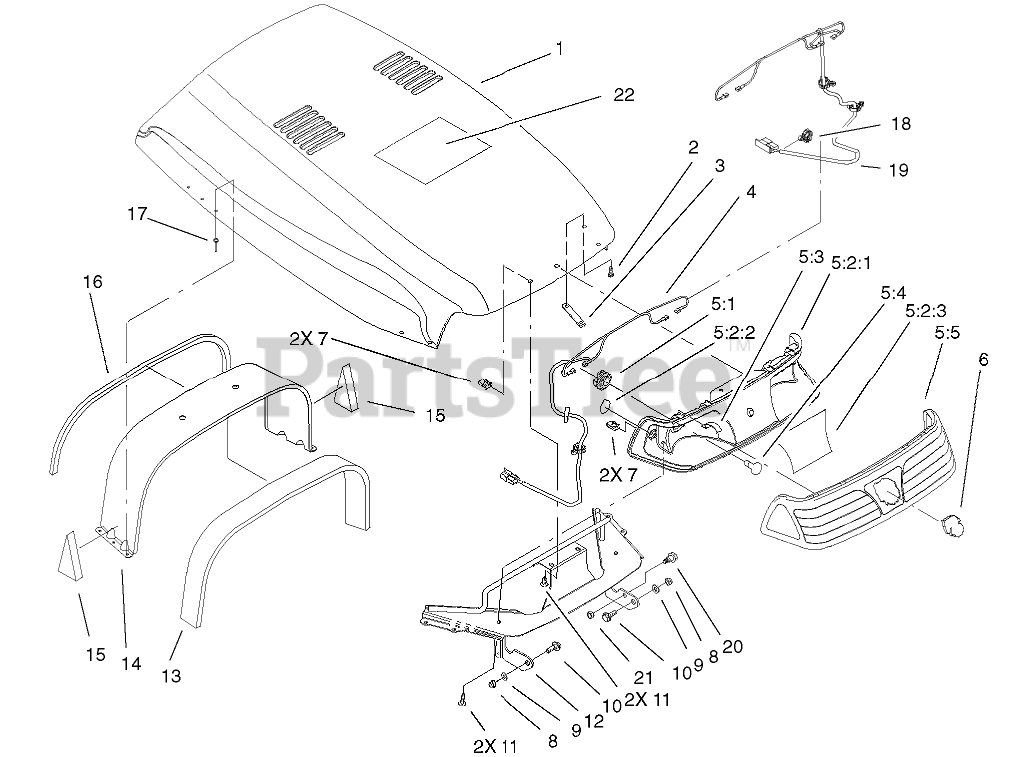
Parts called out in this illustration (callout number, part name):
1	HOOD ASM
2	SCREW
3	PLATE-NUT
4	HARNESS-WIRE, LIGHTS
5:1	SEALED SOCKET ASM
5:2:1	REFLECTOR-HEADLIGHT
5:2:2	DECAL-SIDELIGHT
5:2:3	DECAL-REFLECTOR, HEADLIGHT
5:3	CLIP-RETAINER
5:4	BULB
5:5	LENS-HEADLIGHT
6	EMBLEM
8	NUT-LOCK, NI
9	WASHER-PLAIN
10	SCREW-SHOULDER
11	SCREW-HH
12	BULKHEAD-FRONT
13	SEAL-FOAM, REAR
14	Bulkhead-Rear
15	FOAM-BULKHEAD, LOWER
16	FOAM-TAPE
17	RIVET-POP
20	BOLT-SHOULDER
21	NUT-LOCK, NI
